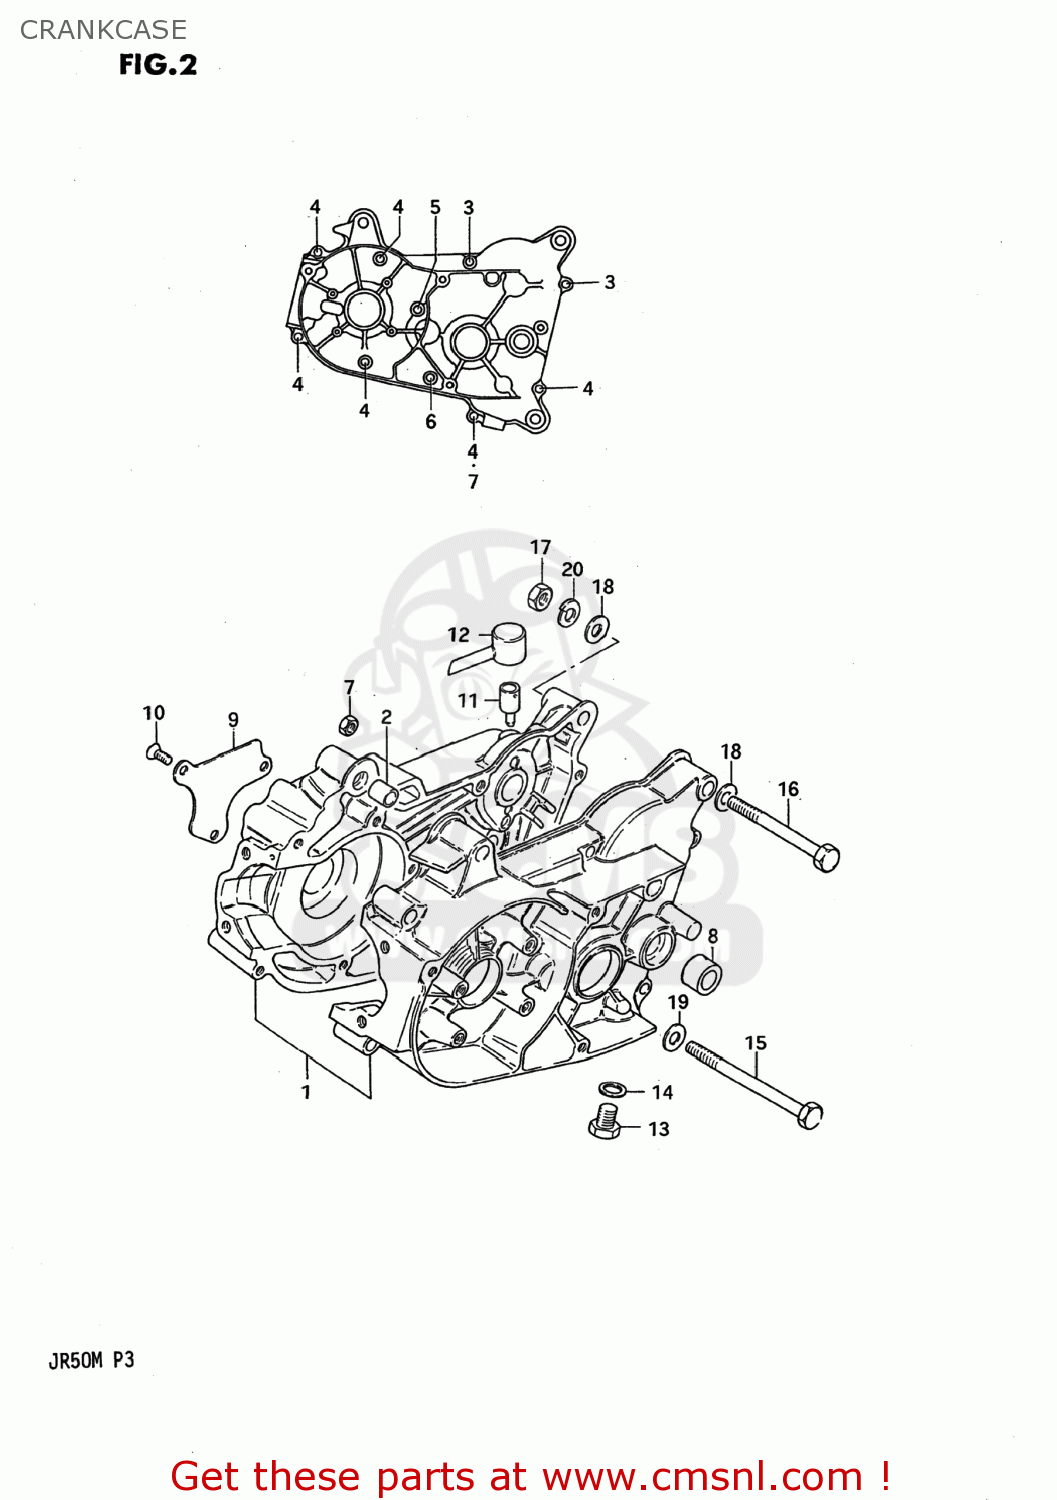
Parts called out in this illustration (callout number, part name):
1	CRANKCASE ASSEMBLY
2	PIN
3	SCREW 6X30
4	SCREW
5	SCREW
6	SCREW
7	NUT 6MM
8	BUSH
9	PLATE,OIL RESERVOIR
10	SCREW
11	PLUG,T/M BREATHER
12	GASKET (NAS)
13	PLUG
14	GASKET(10X14X3.6) (NAS)
15	BOLT
16	BOLT
17	NUT
18	WASHER
19	WASHER
20	LOCK WASHER
